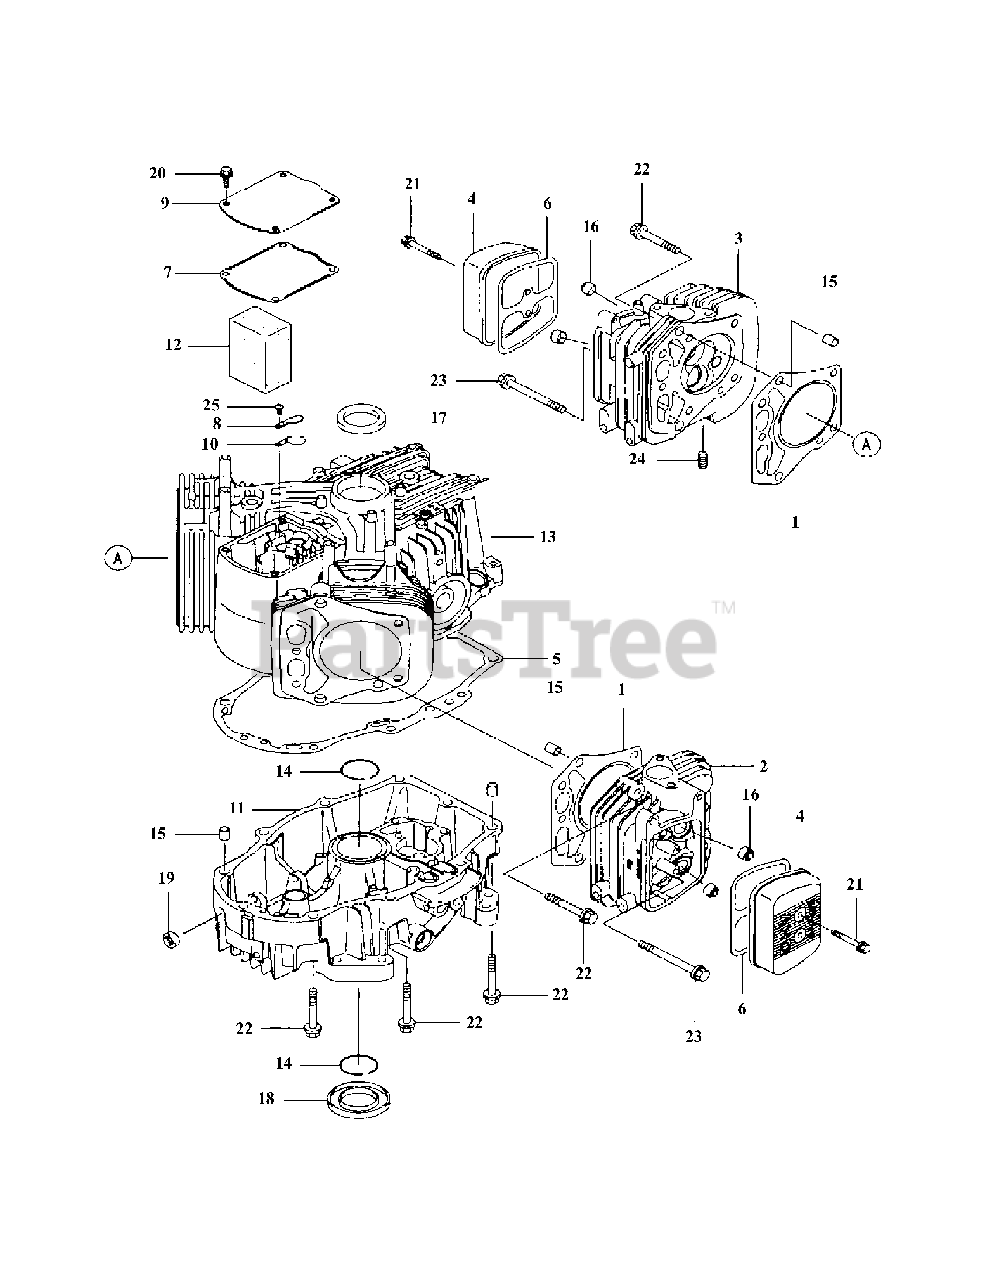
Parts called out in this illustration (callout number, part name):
2	Head-compl,cylinder#2
3	Head-compl,cylinder#1
4	Case-Rocker
5	Gasket, Crankcase Cover
6	Gasket, Rocker Case
7	Gasket, Breather
11	Cover-Crankcase
12	Element-Breather
13	Crankcase
